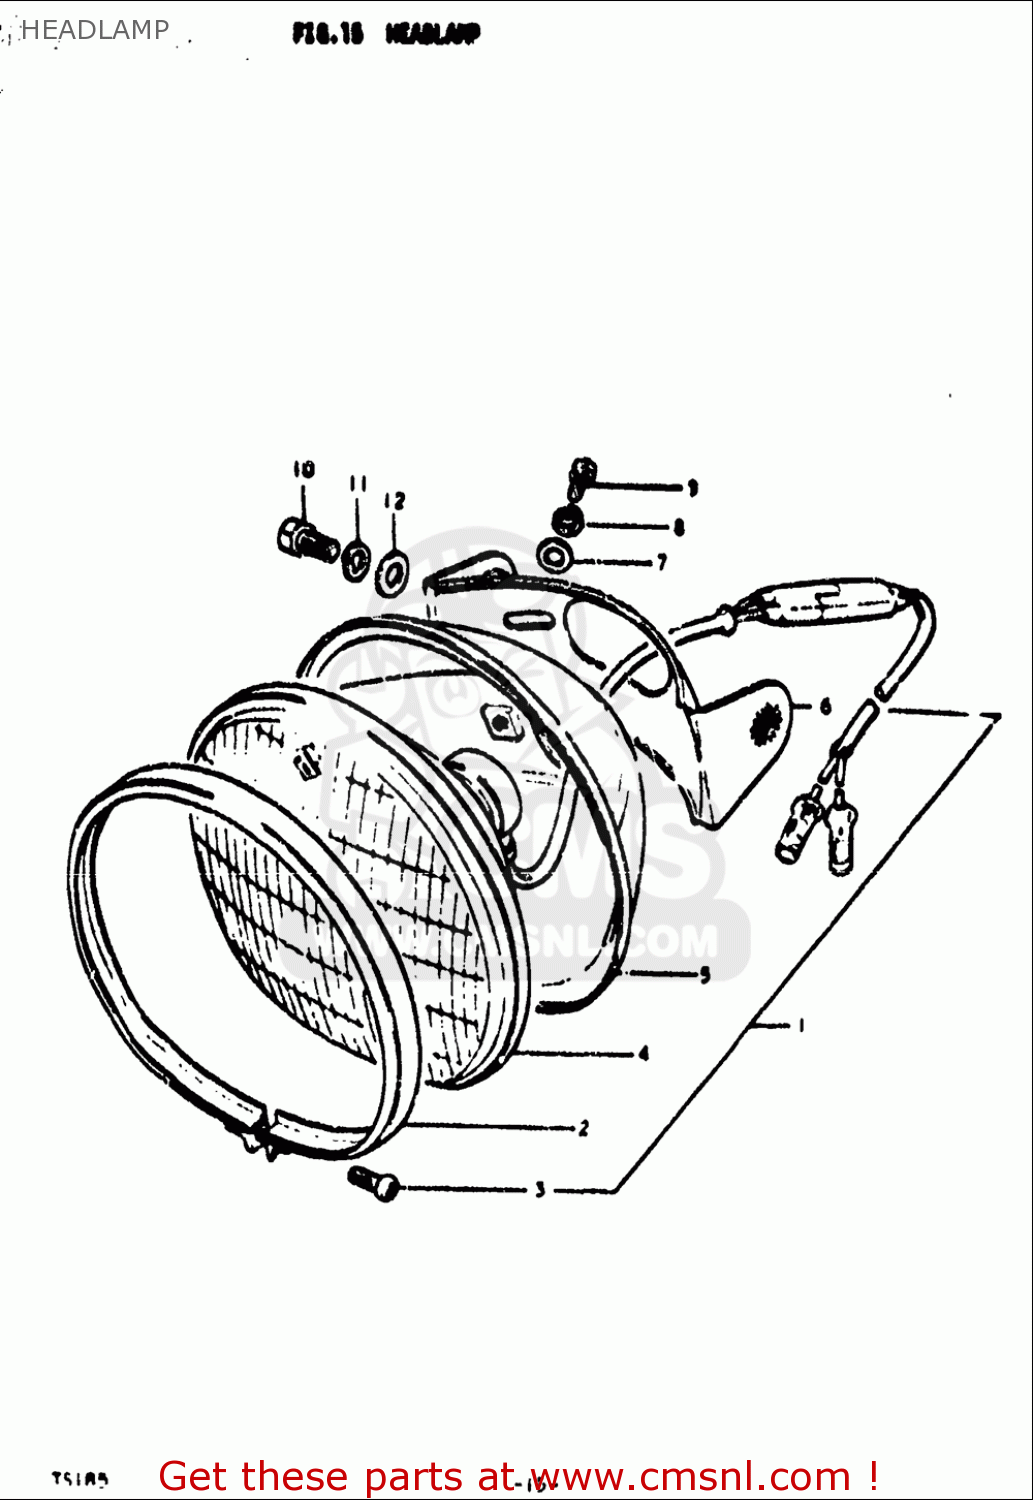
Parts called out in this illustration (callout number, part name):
3	SCREW
7	WASHER
8	WASHER,LOCK
9	BOLT
10	BOLT
11	WASHER,LOCK
12	WASHER (10.5X22X2.3)
